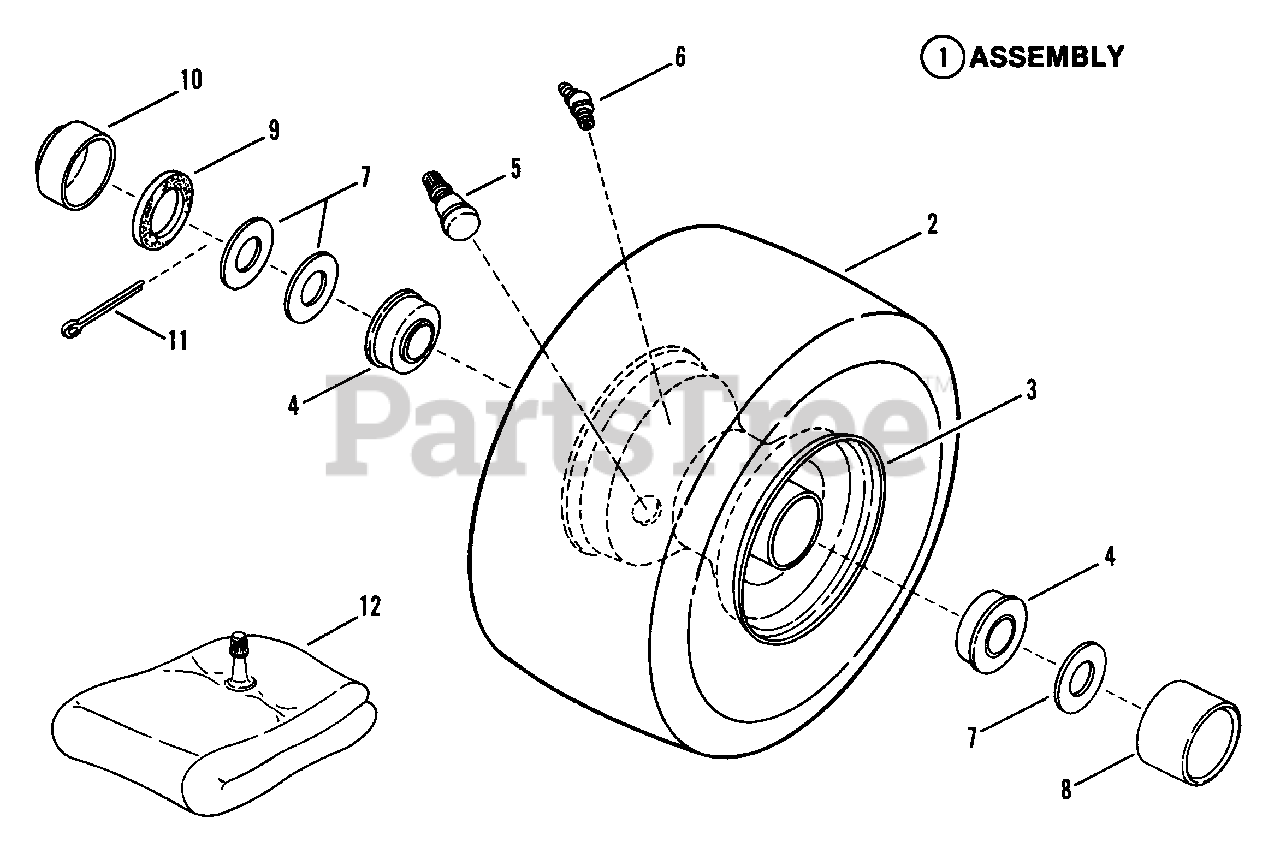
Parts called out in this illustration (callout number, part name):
1	ASSEMBLY, Tire & Rim
2	TIRE, Pneumatic 4.10/3.50 x 4
3	RIM
4	BEARING, Ball
5	VALVE, Air (Snap-in) (8, 10 HP)
6	FITTING Lube
7	WASHER
8	CAP, Hub
9	SEAL, Felt
10	CAP, Dust
11	PIN, 5/32 x 1" Cotter
12	TUBE, Inner
